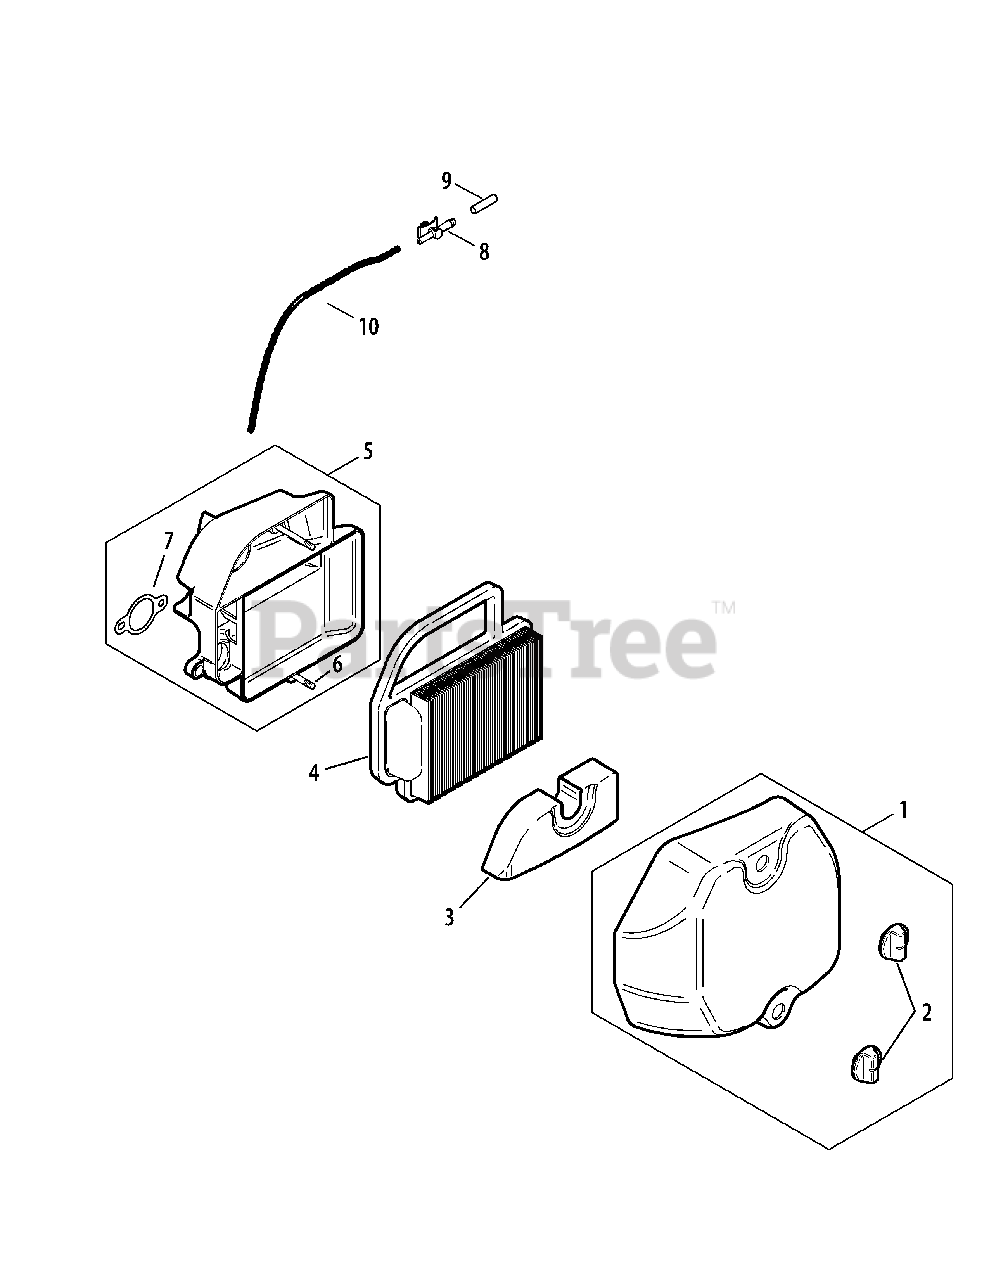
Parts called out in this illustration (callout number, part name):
1	Air Cleaner Cover Kit (Inc. 2)
3	Pre-Cleaner Element (Dry)
4	Air Filter & Pre Cleaner Elements
5	Air Cleaner Base Kit (Inc. 6, 7)
6	Air Cleaner Base Stud
7	Air Cleaner Base Gasket
8	Evaporative Connector
10	Hose, Evaporative 20"
